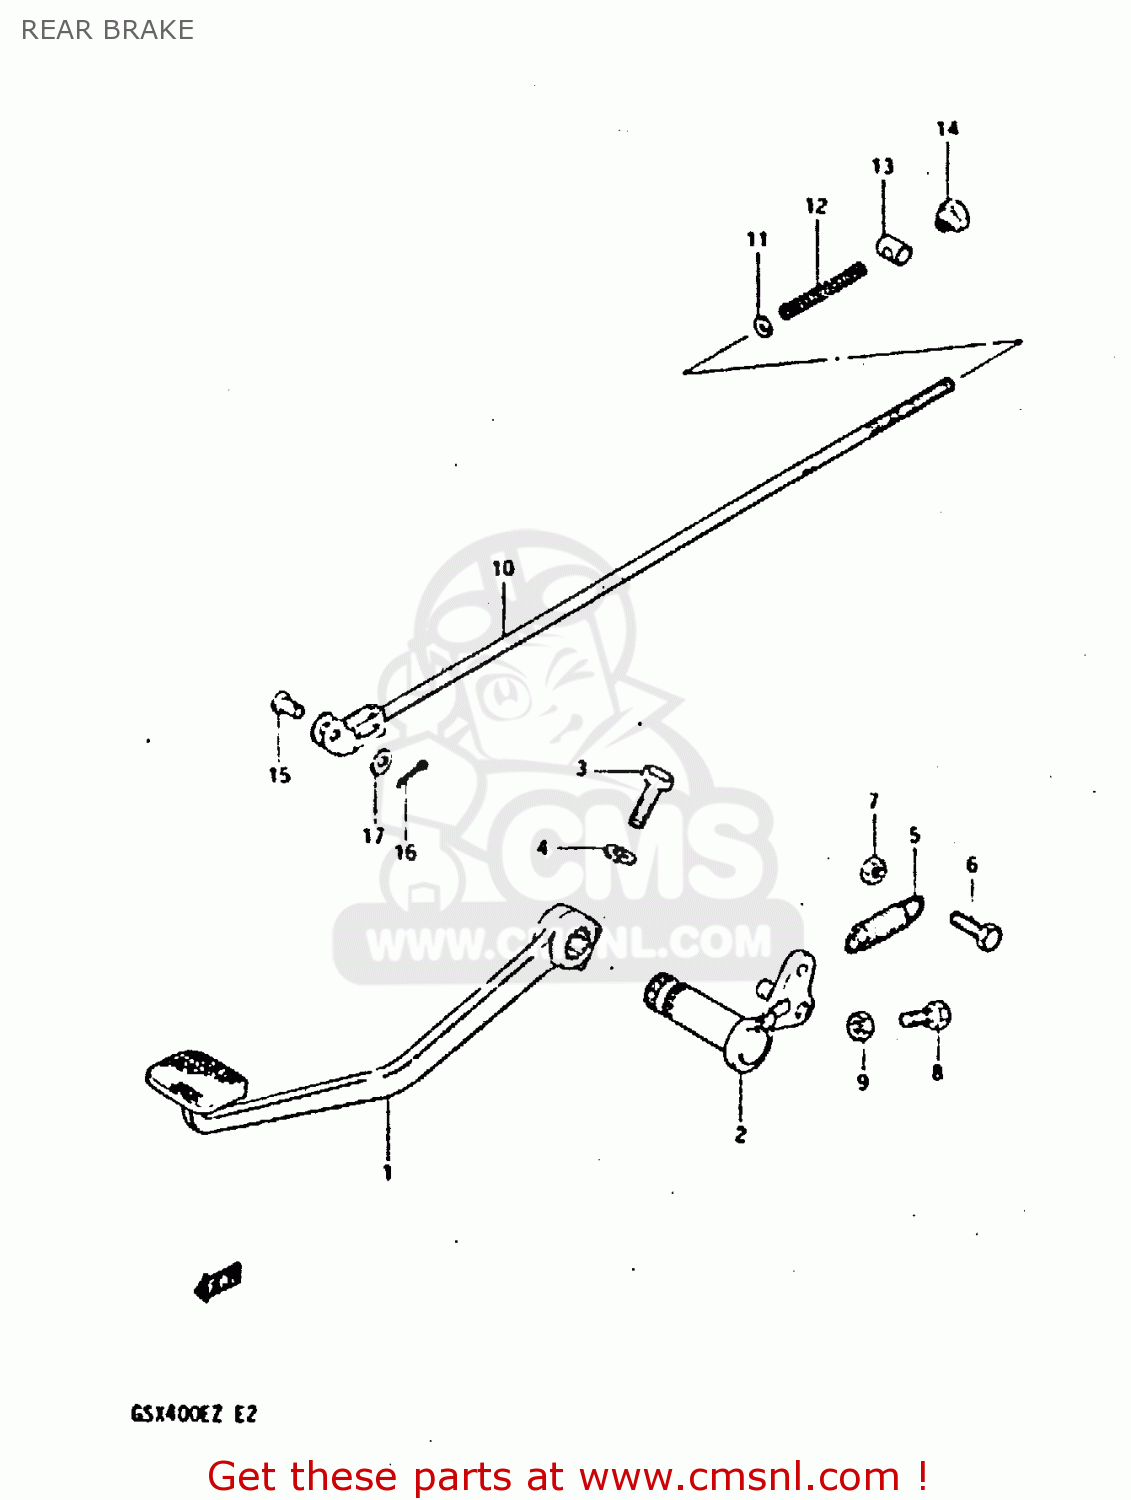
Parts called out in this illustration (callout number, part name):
1	PEDAL,BRAKE
2	ARM,BRAKE PEDAL
3	BOLT
4	LOCK WASHER
5	SPRING
6	BOLT
7	NUT
8	BOLT
9	NUT
10	ROD ASSY,RR BRAKE
11	WASHER
12	SPRING
13	PIN
14	NUT
15	PIN(L:13.5)
16	PIN 20X20
17	WASHER
